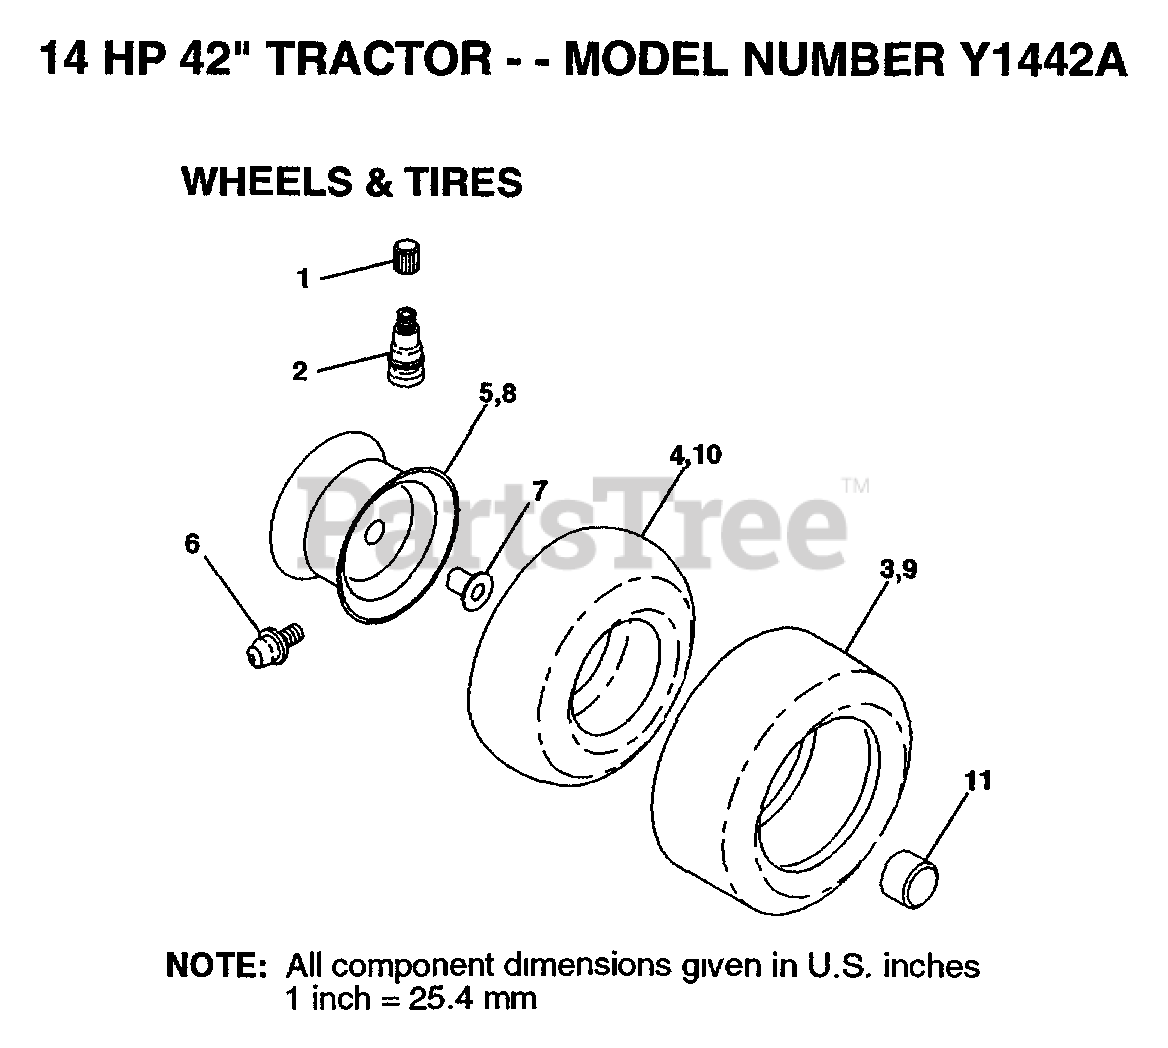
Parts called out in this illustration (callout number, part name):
1	VALVE CAP
2	VALVE STEM LT
4	TUBE.5.3/4.5/6
6	FITTING LT
7	"FLANGE, BEARING"
10	TUBE.18X9.5-8
11	HUB CAP
